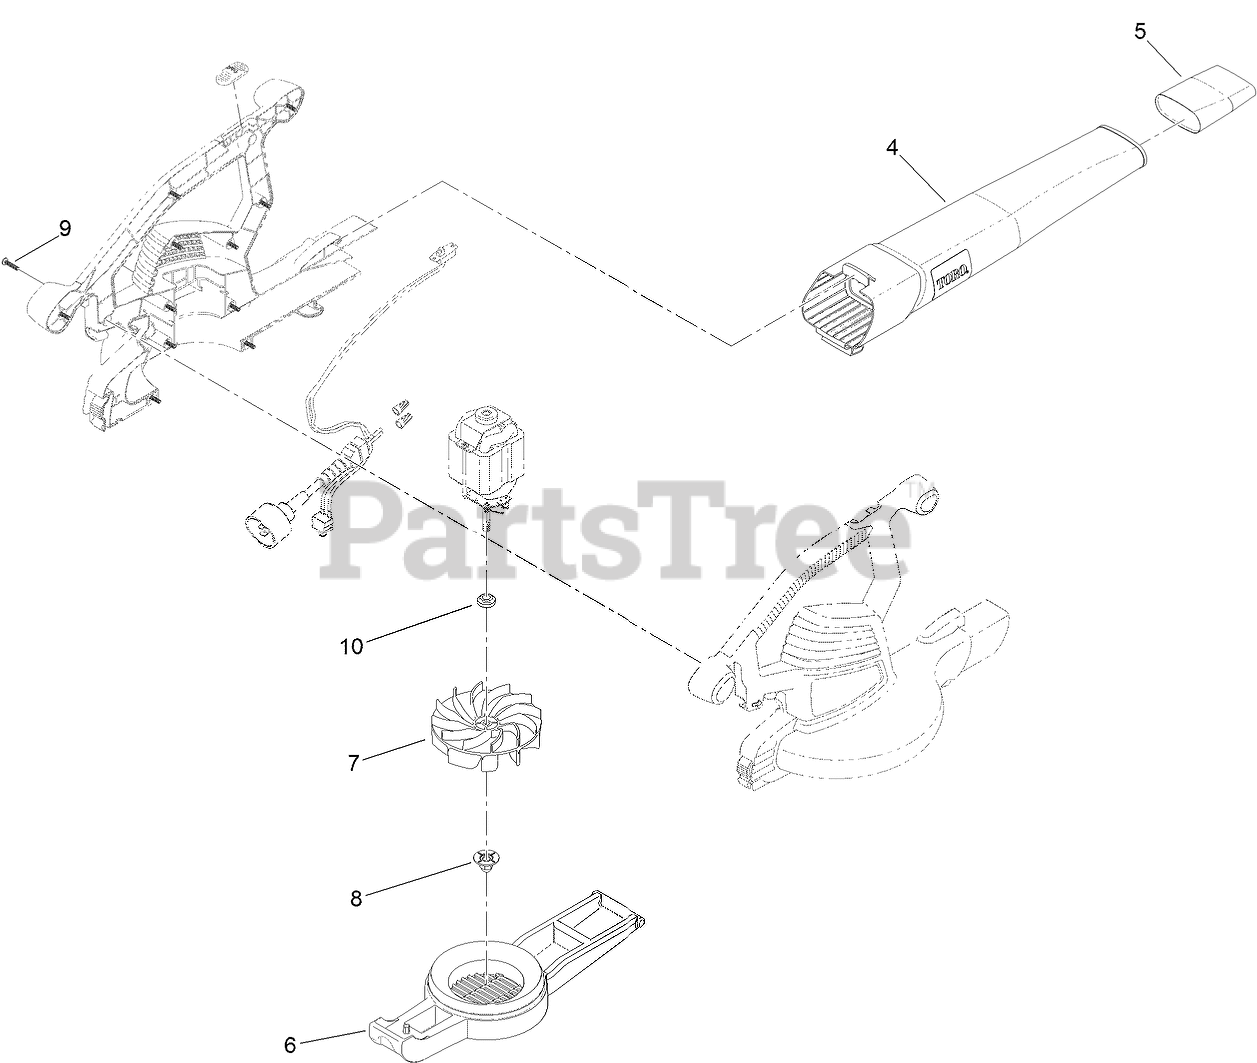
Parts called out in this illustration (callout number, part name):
4	TUBE-BLOWER
5	TUBE-INSERT, SUPER
6	COVER-INLET
7	IMPELLER
8	NUT-IMPELLER
9	SCREW-PPH
10	BUSHING-MOTOR
